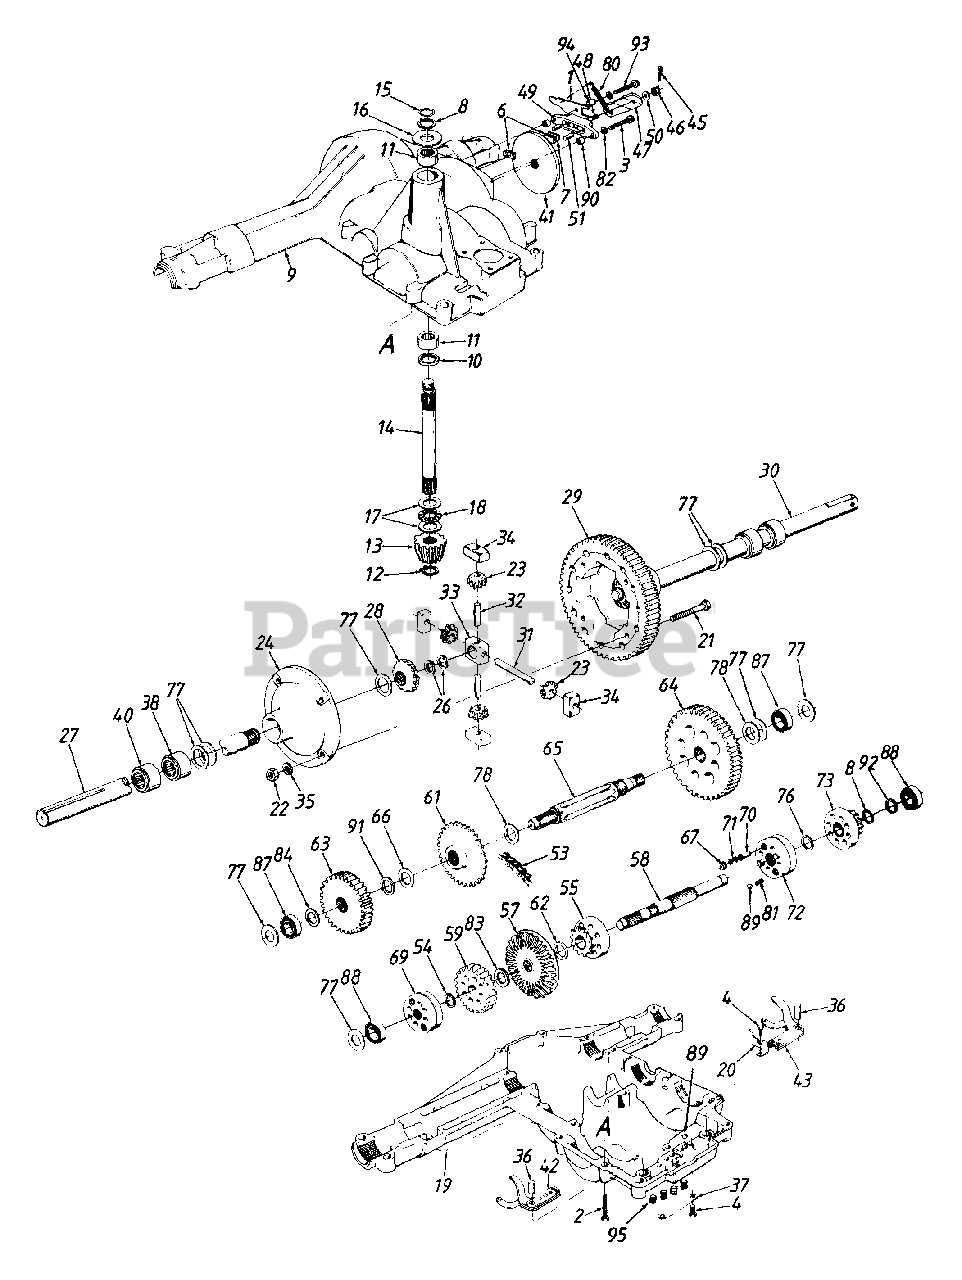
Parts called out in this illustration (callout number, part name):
1	Brake Return Bracket
2	Hex Bolt 1/4-20 x 1.25" Lg.
3	Hex Bolt 1/4-20 x 1.5" Lg. (Gr. 5)
4	Hex Wash. Tap Scr. 1/4-20 x .5" Lg.
6	Brake Puck
7	Puck Plate
8	Retainer Ring
9	Upper Housing
10	Oil Seal
11	Needle Brg. 5/8" I.D. x 7/8" O.D.
12	Snap Ring
13	Input Pinion 15T
14	Input Shaft
15	Wire Ring
16	Thrust Washer 5/8" I.D.
17	Thrust Washer
18	Thrust Bearing
19	Lower Housing
20	Shift Guide
21	Hex Bolt 3/8-24 x 2.0" Lg.
22	Hex L-Nut 3/8-24 Thd. (Gr. 5)
23	Differential Gear 10T
24	Differential Housing Cover Ass'y.
26	Retainer Ring
27	Axle R.H.
28	Differential Gear 14T
29	Differential Bull Gear 60T
30	Axle L.H.
31	Cross Shaft
32	Cross Shaft - Special
33	Differential Pinion Block
34	Differential Thrust Block
35	Spr. Wash. .39" I.D. x .62" O.D.
36	Shift Pin
37	Spring Plate
38	Axle Bearing Ass'y.
40	Axle Bearing Ass'y.
41	Brake Disc
42	Shift Arm Ass'y. - R.H.
43	Shift Arm Ass'y. - L.H.
45	Cotter Pin 3/32" Dia.
46	Castle Nut 5/16-24 Thd.
47	Brake Actuating Arm
48	Sq. Hd. Bolt 5/16-24 Thd.
49	Brake Yoke
50	Fl-Wash. 11/32" I.D. x 7/8" O.D.
51	Brake Actuating Pin
53	#420 Chain 1/2 Pitch x 28 Links
54	Retainer Ring
55	Reverse Sprocket Ass'y.
57	Bevel Gear 47T
58	Drive Shaft
59	Spur Gear Ass'y.
61	Sprocket 22T
62	Fl-Wash. .81" I.D. x 1.18" O.D.
63	Spur Gear 31T
64	Spur Gear 45T
65	Output Shaft 9T
66	Spacer
67	Shift Spring Plug
69	Forward Shift Collar
70	Drive Pin
71	Drive Spring
72	Creeper Shift Collar
73	Creeper Collar Plate Ass'y.
76	Fl-Wash. .65" I.D. x .97" O.D.
77	Fl-Wash. 1" I.0. x 1.56" O.D. x .010" Thk.
78	Fl-Wash. 1.0" I.D. x 1.56" O.D.
80	Ext. Spring 1.14" Lg.
81	Detent Spring
82	L-Wash. 1/4" I.D.
83	Fl-Wash. 5/8" I.D. x 1.0" O.D.
84	Fl-Wash. .68" x 1.12"
87	Ball Brg. .669" I.D.
88	Ball Bearing
89	Ball Detent .25" Dia.
90	Spacer .254" I.D. x .5" O.D.
91	Fl-Wash. .69" I.D. x 1.06" O.D.
92	Fl-Wash. 5/8" I.D. x 1.0" O.D. x .020" Thk.
93	Hex Wash Hd. Patch Bolt 1/4-20 x 2-1/4" Lg.
94	Spacer .256" I.D. x .75" O.D.
95	Detent Spring
